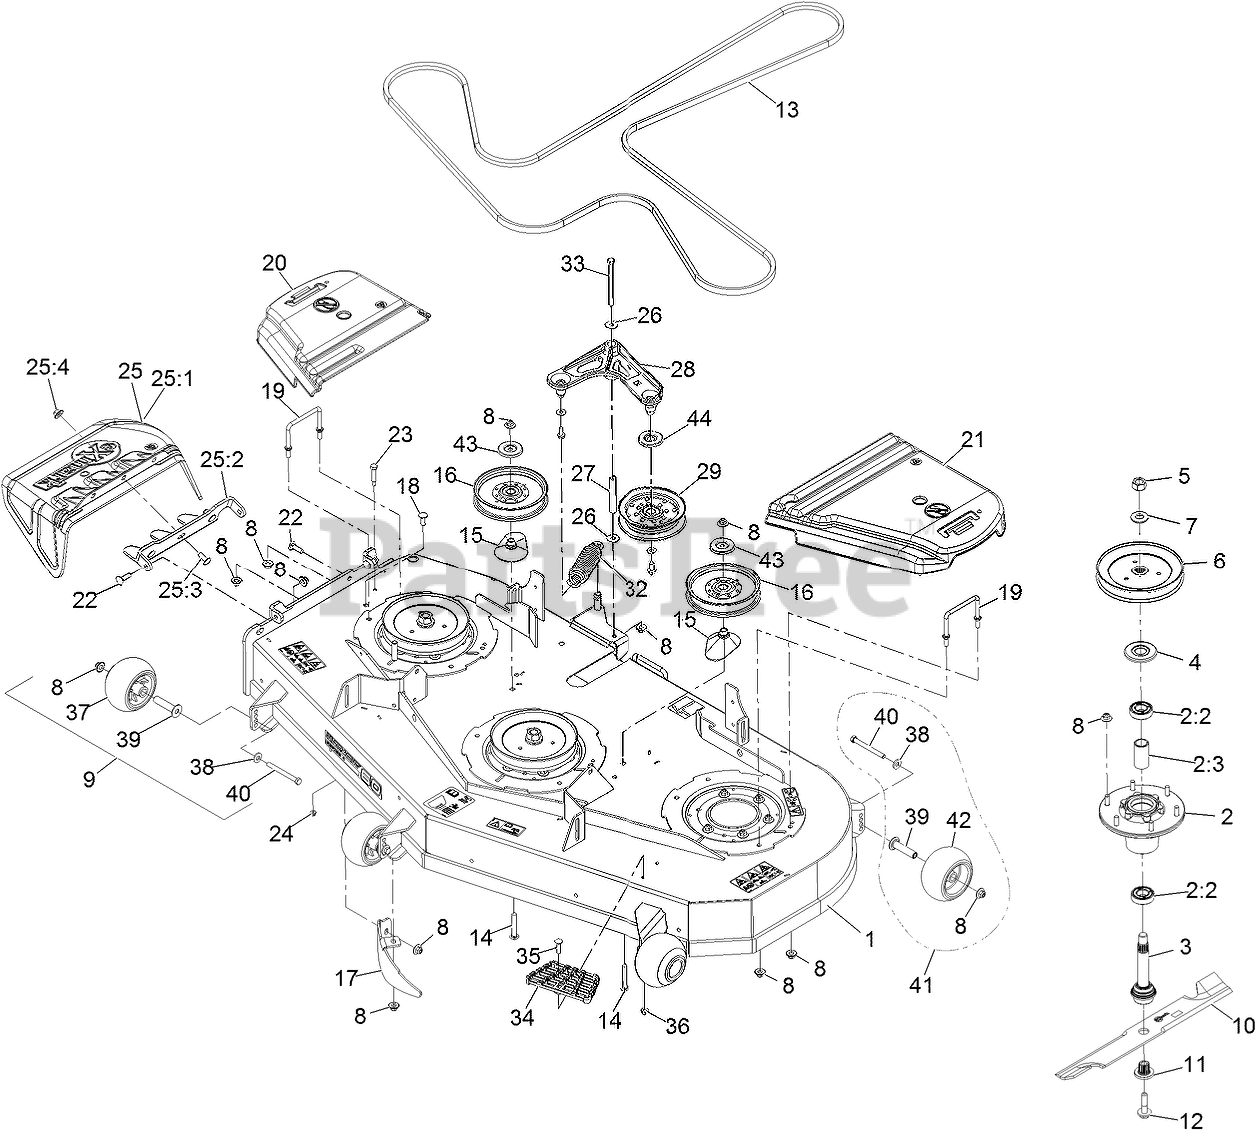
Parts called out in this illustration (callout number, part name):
1	ASM-DECK W/DECALS 604
2	ASM-CUTTER HSG WITH BEARINGS
2:2	BEARING-BALL
2:3	SPACER-BEARING
3	ASM-SPINDLE AND SEAL
4	GUARD,BEARING TOP .989
5	NUT-HEX
6	SHEAVE,BLADE DRIVE 7.25
8	Nut-Nyloc 3/8-16 Flg
9	KIT, ANTI-SCALP ROLLER
10	Blade-Extreme 2, 20.50"
11	BUSHING,SPLINED
12	SCREW,SEMS 1/2-20 X 2.19
14	SCREW-CARR
15	SPACER-PULLEY
16	IDLER-PULLEY, FLAT 6.00X1.00
17	DOGLEG - LZ60
18	SCREW-CARR
19	WIREFORM-COVER
20	COVER-BELT, RH
21	COVER-BELT, LH
22	BOLT-CARR
23	BOLT-SHOULDER
25	ASM,DISCHARGE CHUTE
25:1	CHUTE,DISCHARGE
25:2	BRACKET,DISCHARGE CHUTE
25:3	SCREW-CARR
25:4	Nut-Nyloc 3/8-16 Flg
27	BUSHING
28	IDLER ARM ASM
29	IDLER-PULLEY, FLAT
32	SPRING-EXTENSION
33	SCREW-HH
34	STEP-DECK
35	Bolt-Carriage 5/16-18 X 1 1/4
36	NUT-HF, NI
37	ROLLER-SCALP, ANTI
38	WASHER-BELLEVILLE
39	AXLE, ROLLER
40	SCREW-HH 3/8-16 X 3 3/4 GR 8
41	KIT-ANTISCALP ROLLER
42	ROLLER-SCALP, ANTI
43	SHIELD-DUST
44	SHIELD-GUARD, DUST
